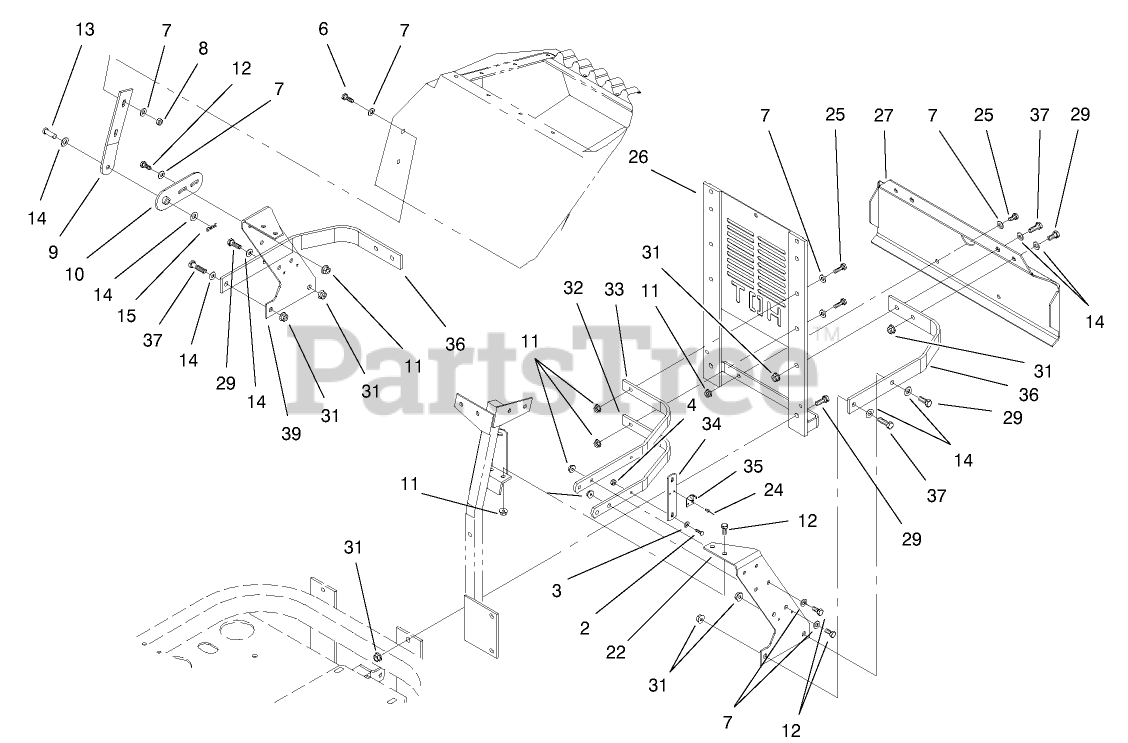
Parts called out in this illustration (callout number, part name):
2	Screw-HSBH
3	WASHER-FLAT
4	NUT-LOCK, NI
6	SCREW-HH
7	WASHER-PLAIN
8	NUT-LOCK NI
9	Plate-Hinge, Hood
10	Shackle Hinge ASM
11	NUT-HF
12	SCREW-HH
13	Pin-Clevis
14	WASHER-FLAT
15	Pin-Hair Cotter
22	Plate-Mount, Radiator
24	Rivet
25	SCREW-HH
26	Rear Radiator Mount ASM
27	Bumper-Rear
29	SCREW-HH
31	NUT-HHF, WHIZ
32	Rib-Top
33	Rib-Bottom
34	Bar-Hook, Latch
35	Keeper-Latch, Rubber
36	Bar-Frame, Radiator Mount
37	SCREW-HH
39	Plate-Mount, Radiator
